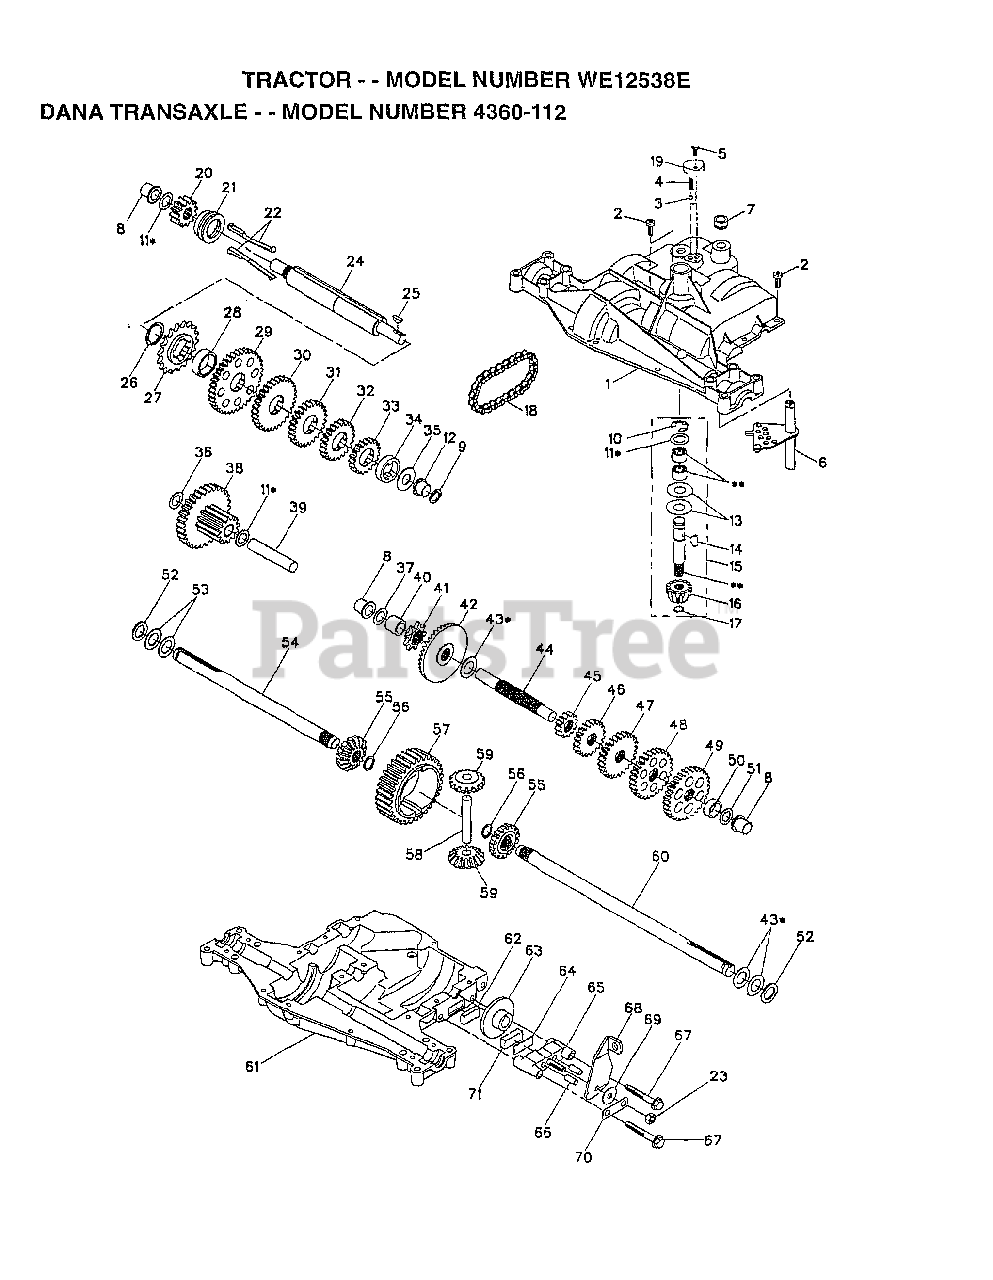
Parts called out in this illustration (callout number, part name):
1	HOUSING.UPPER.DANA.(5305J)
4	"SPRING, DETENT LT"
5	SCREW.TAPPING.1/4-20X.734
6	KIT SHIFTER ASM
9	SEAL.OIL.DAN.5508
10	RETAINING RING LT
11	ASM KIT SHIM 4689
12	BEARING.FLNG.5511
13	WASHER T
14	KEY WOODRUFF-DANA
15	AS KIT INPUT SHFT
16	PINION 14T T
17	"RING,RETAINING LT"
18	"CHAIN,24 PTCH LT"
19	COVER.DETENT.(5584)
20	GEAR.SPUR.12T.(5627)
21	CLUTCH.COL.5467
22	ASM KIT CLTCH KEY
23	NUT.LOCK.5/16-24
24	SHAFT INTERM DANA
25	WOODRUFF KEY
26	"RING,RETAINING LT"
27	SPROCKET 18T T
28	SPACER YT
29	GEAR SPUR 37 TTH
30	GEAR SPUR 30T
31	GEAR 25T LT
32	GEAR SPUR 22 TT
33	SPUR GEAR 19T
34	SPACER
35	"WASHER, PLAIN LT"
36	WASHER 045
37	WASHER 031
38	ASSY.GEAR.6153 12T&30T
39	SHAFT IDLER
40	SPACER T
41	SPROCKET 9T LT
43	ASM KIT SHIM
44	SHAFT T
45	GEAR SPUR 12 TTH
46	GEAR SPUR 20T
47	"GEAR, SPUR 25T LT"
48	GEAR 28T T
49	"GEAR, SPUR 31T LT"
51	WASHER 060
52	NEOPRENE WASHER
53	WASHER 031
54	AXLE.LH(5528-1)
55	GEAR 15T T
56	RING.RETAINING.(5270)
58	SHAFT T
59	GEAR 1ST T
60	AXLE.RH.(5528-2) DANA
61	HOUSING LOWER TNS
62	PUCK T
63	BRAKE DISC. T
64	SPACER LT
66	PIN T
67	SCREW.(5562) .5/16-18X2.35
69	WASHER LT
70	BRACKET, ANTI-ROTATION
71	PUCK T
